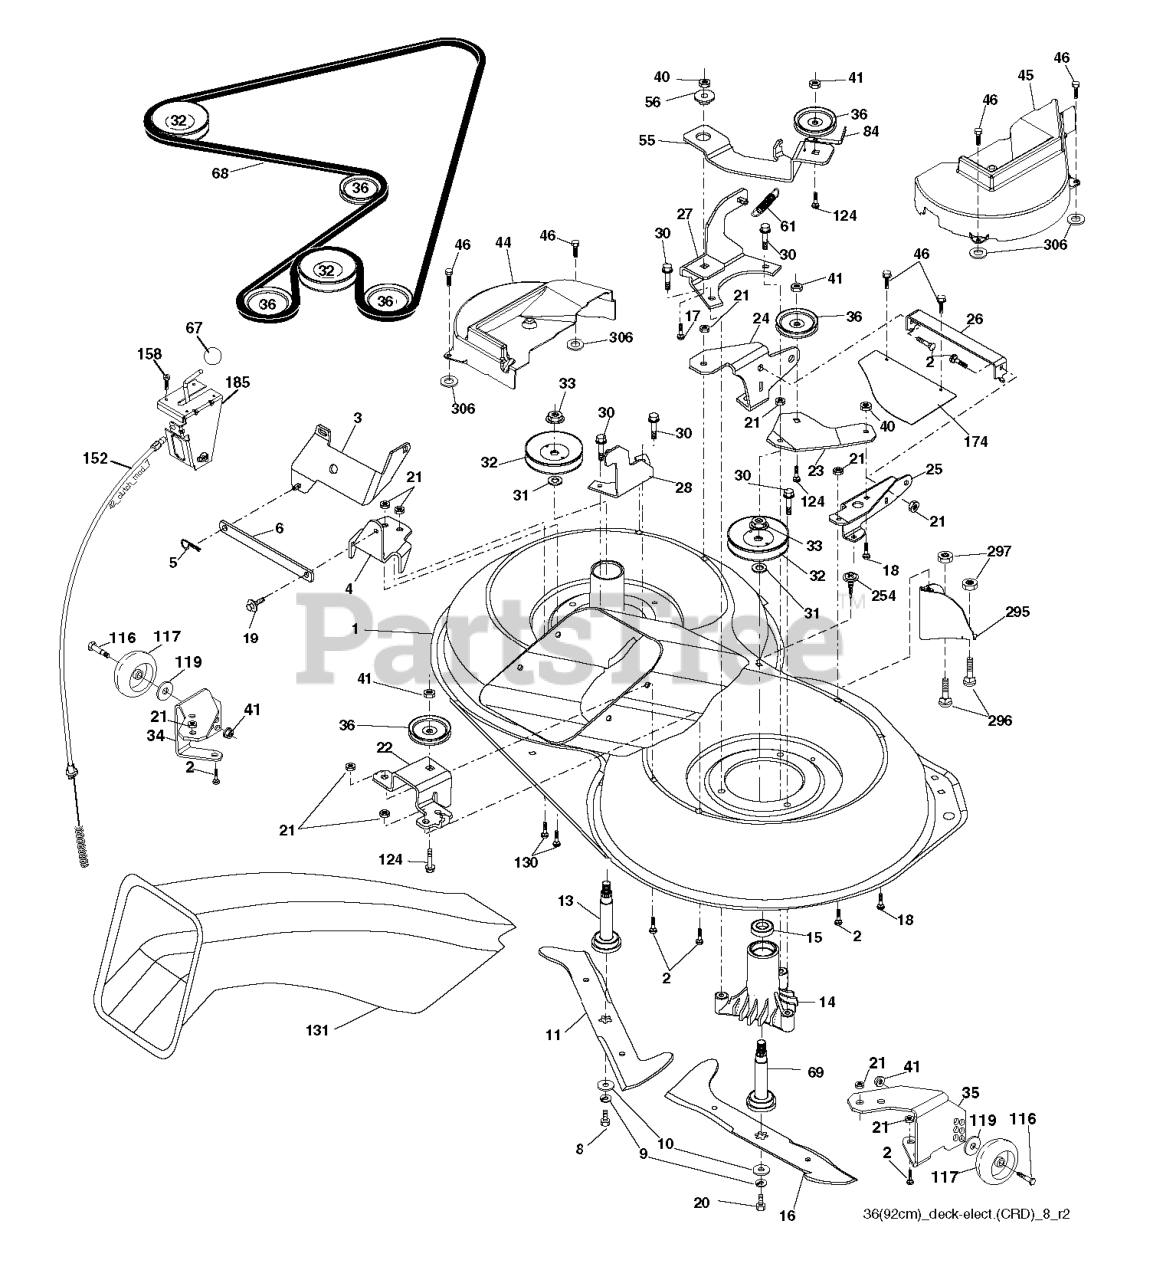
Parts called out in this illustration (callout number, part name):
2	RP BOLT 5/16-18 X3/4 ZN/YEL GR
5	RETAINER-SPRNG RB
6	BAR.SWAY.92.CRD
8	BOLT.3/8-24X1.25 GR8
9	LOCKWASHER
10	WASHER.BLADE
13	SHAFT ASM VENT
14	HOUSING.MANDREL.VENTED (MACHD)
17	BOLT.3/8-14X1.25
18	BOLT
19	BOLT SHD 5/16-18
20	BOLT.3/8-24X1.25GR8. LHTHRD
21	LOCKNUT
26	SUPPORT
30	SCREW, WASHER HEAD
31	WASHER.SPACER.MANDREL
32	PULLEY MANDREL
33	NUT.FLANGE.LOCK.TOP
36	PULLEY.IDLER.4.25
41	NUT LOCK FLG 3/8-16 UNC
46	SCREW.1/4-20X5/8
55	ARM.IDLER.92 CRD.2006
56	SPACER.RETAINER.MOWER
61	SPRING
67	KNOB T (3/8 HOLE)
68	BELT.DRIVE.92CM.CRD.2006
69	SHAFT.ASM.W/LWR.BRG.RH.THREAD
84	KEEPER, BELT IDLER
116	BOLT.SHOULDER.3/8-16X3-5/8.
117	RP WHEEL. GUAGE RALLY
119	WASHER
124	BOLT.3/8-16X1.50
130	BOLT.CARR.SQNK.5/16-18UNC.X3/4
131	CHUTE BAGGER
158	SCREW
185	HEAD ASM. CABLE CLUTCH
254	SCREW 3/8-16X1
296	BOLT
297	NUT CENTERLOCK
306	PALNUT 1/4
